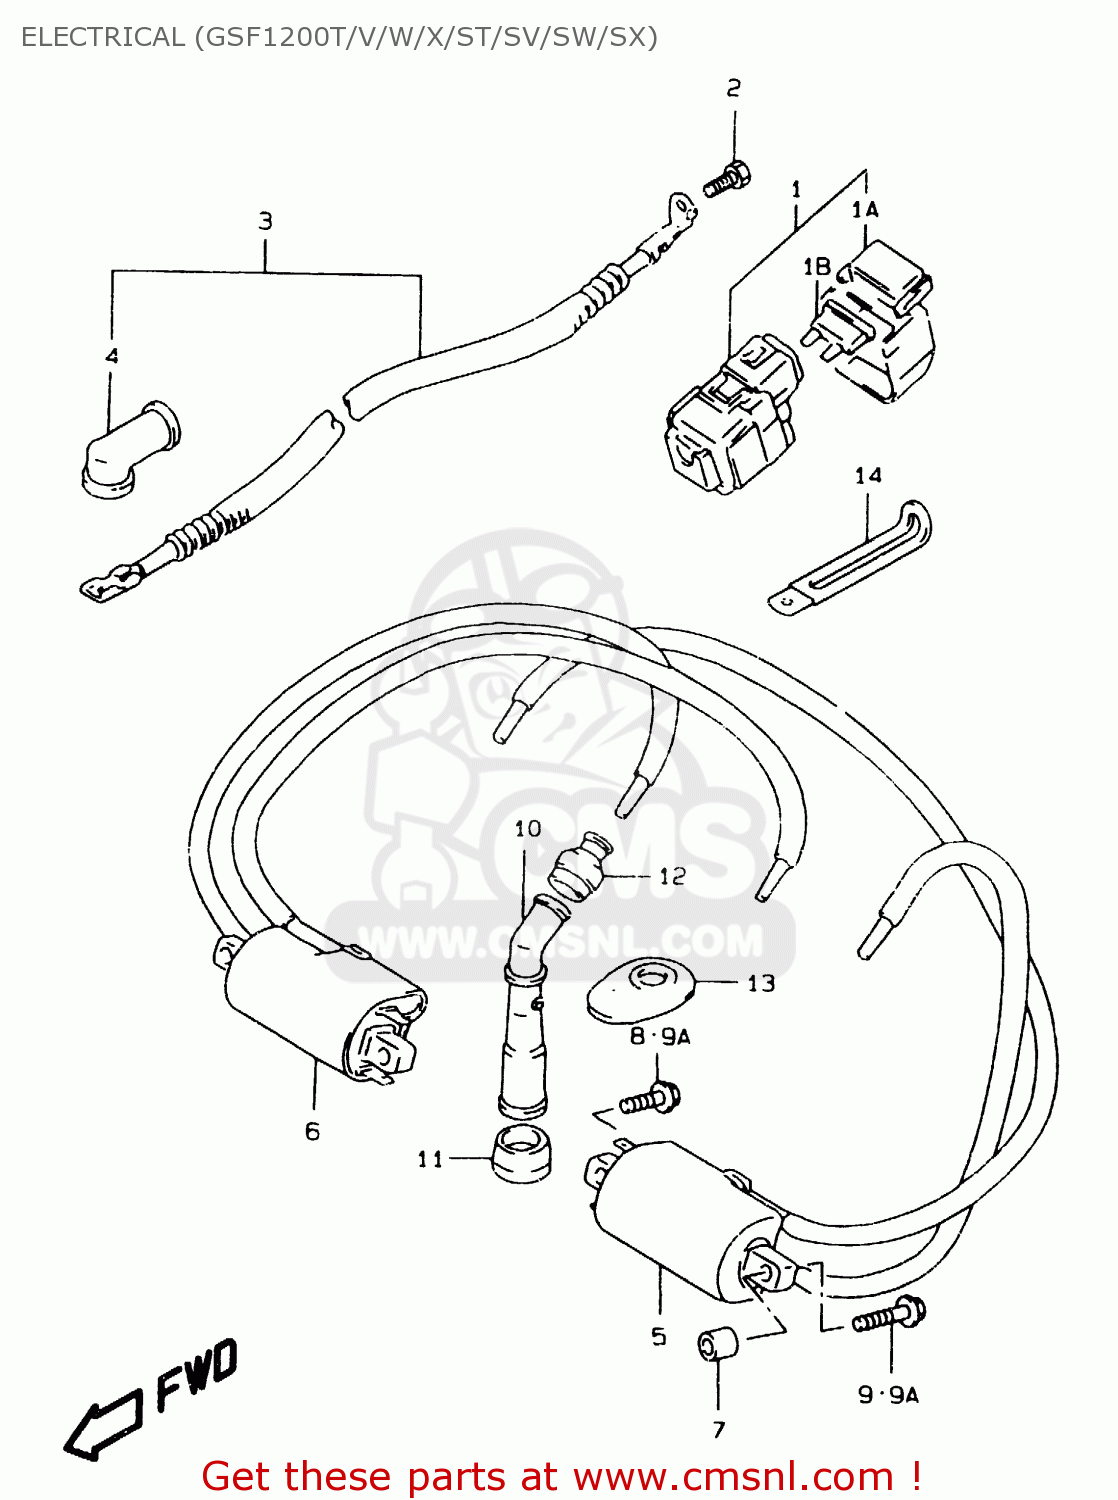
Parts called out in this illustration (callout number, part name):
1	RELAY ASSY,STARTING MOTOR
1A	COVER,STARTER RELAY
1B	FUSE(30A)
2	SCREW(6X8)
3	WIRE,STARTER MOTOR LEAD
4	CAP,STARTER MOTOR LEAD
5	COIL ASSY,IGNITION
6	COIL ASSY,IGNITION
7	SPACER(6X12X10)
8	BOLT
9	BOLT
9A	BOLT
10	CAP,SPARK PLUG
11	SEAL,SPARK PLUG CAP
12	SEAL,HIGH TENSION CORD
13	COVER,SPARK PLUG CAP
14	CLAMP(L:65)
